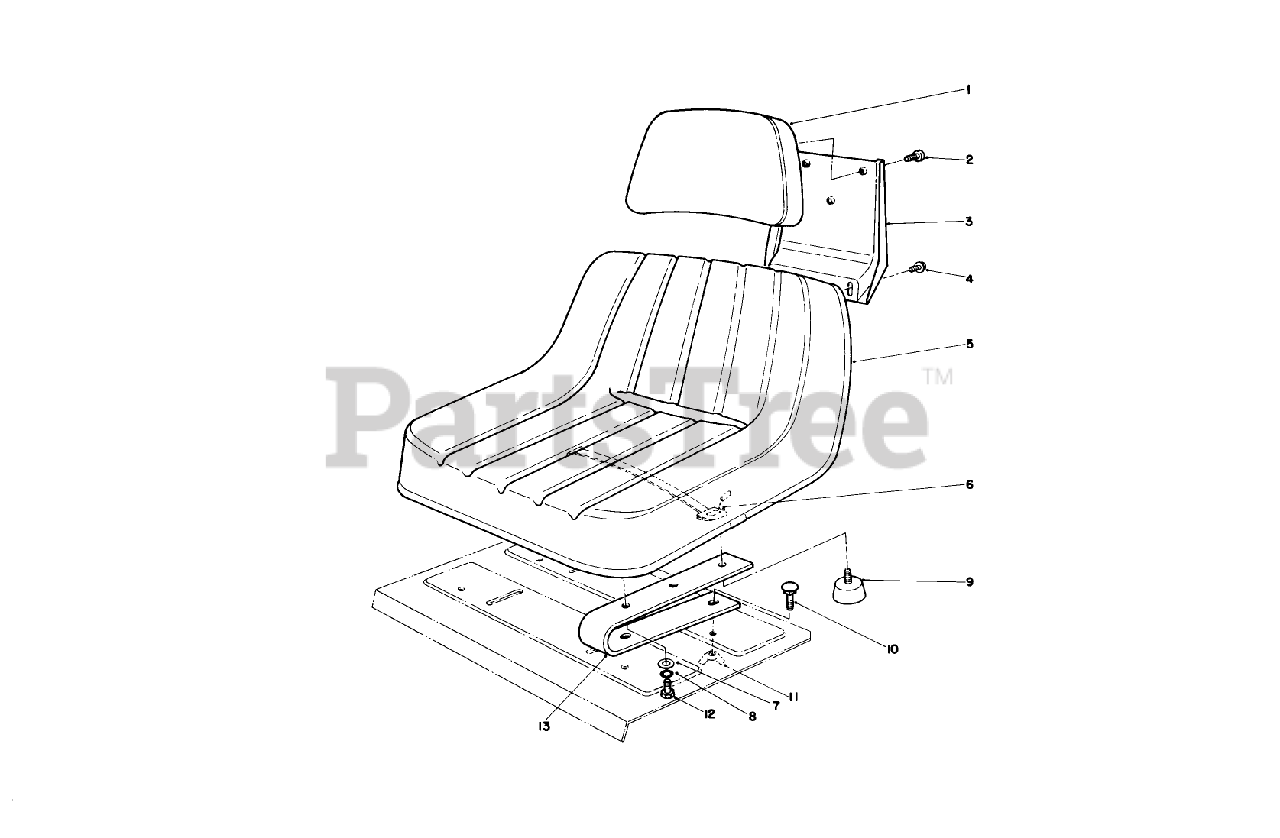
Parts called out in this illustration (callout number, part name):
1	Back Rest
2	Screw-Phillip Head
3	PLATE
4	SCREW-HHF
5	Seat
6	SWITCH-SEAT
7	WASHER-PLAIN
8	WASHER-LOCK
9	RUBBER BUMPER
10	SCREW-CARR
11	NUT-WING, LOCK
12	SCREW-HH
13	Spring Seat
